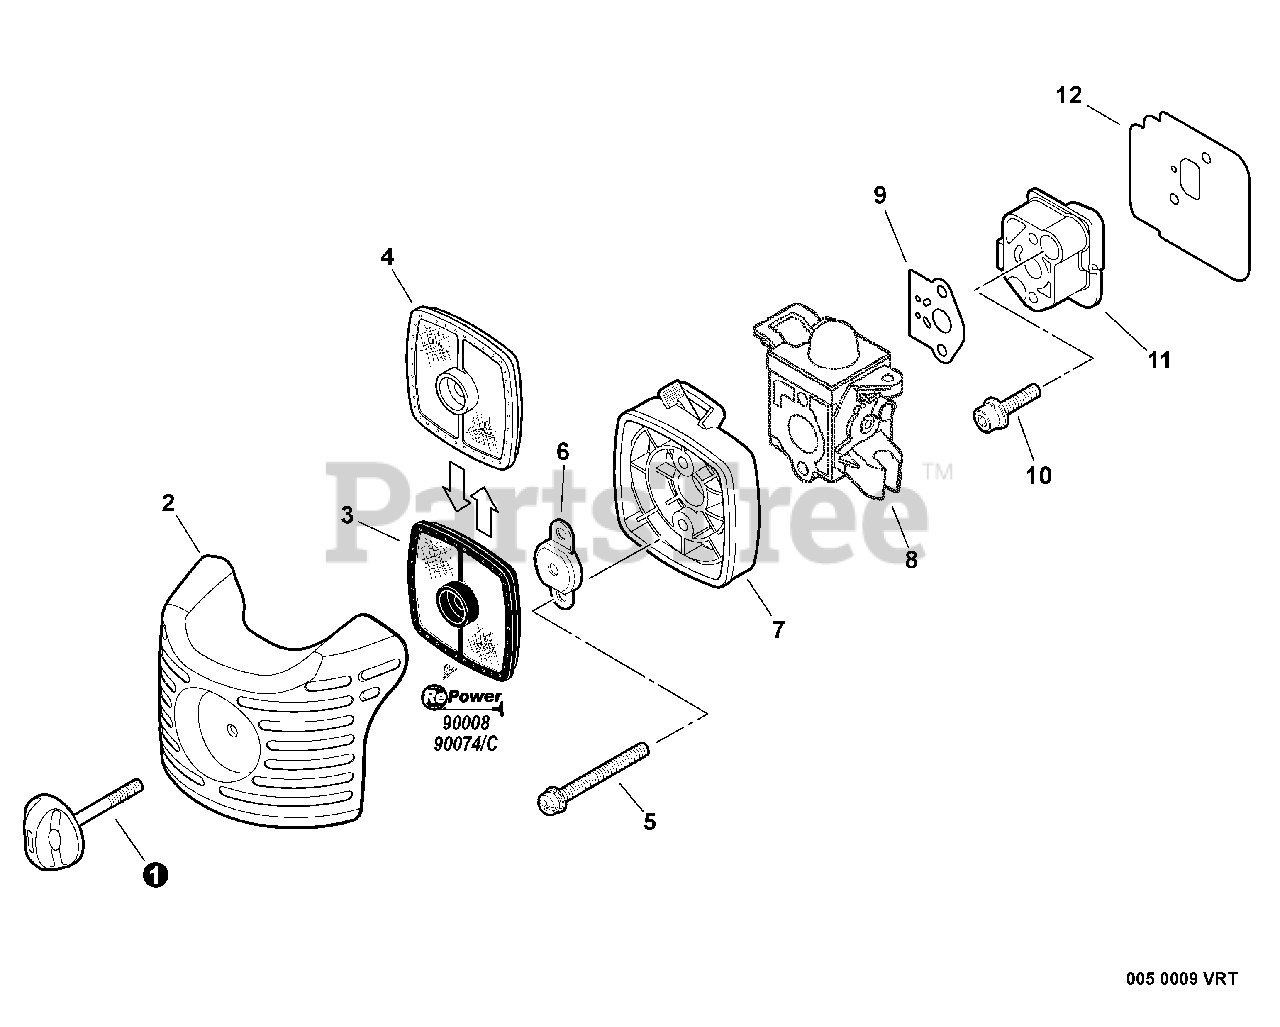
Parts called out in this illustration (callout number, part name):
1	THUMBSCREW
2	COVER, AIR FILTER
3	FILTER, AIR - DOUBLE LAYER
4	FILTER, AIR - SINGLE LAYER
5	SCREW 5×65
6	PLATE, PREVENT
7	CASE ASSY, AIR FILTER
8	CARBURETOR
9	GASKET, INTAKE
10	INSULATOR, INTAKE
11	BOLT 5×25
12	HEAT SHIELD, INTAKE
13	TUNE-UP KIT - REPOWER
14	FILTER KIT - REPOWER
